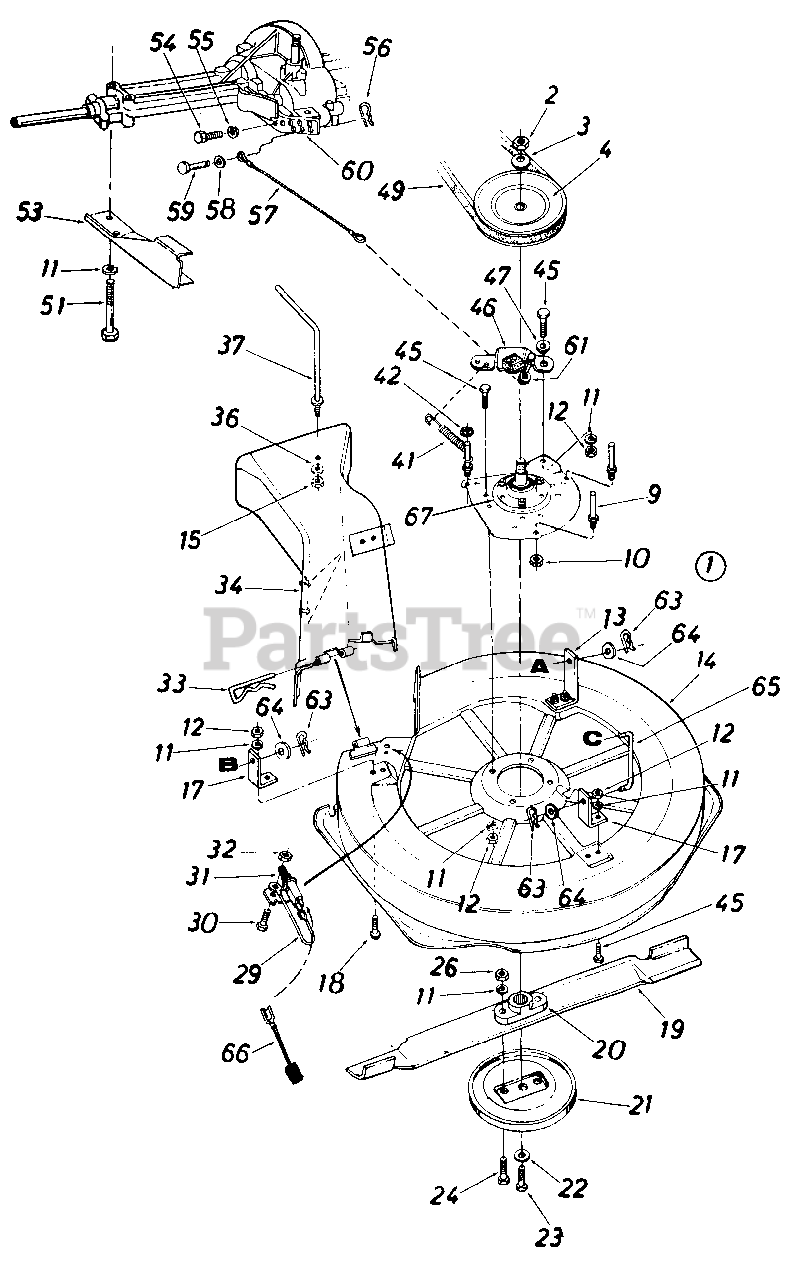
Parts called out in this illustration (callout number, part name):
1	30" R.D. Deck Ass'y. Comp.
2	Hex Jam Nut 5/8-18 Thd.
3	Bell-Wash. .630" I.D. x 1.25"
4	5/8 V-Pulley .75" I.D. x .7"
9	Stud 3/8-16 x 2.75" Lg.
10	Hex Jam Nut 3/8-16 Thd.
11	L-Wash. 5/16" I.D.
12	Hex Nut 5/16-18 Thd.
19	30" High Lift Blade
20	Blade Adapter
21	Scalp Plate
22	L-Wash. 3/8" I.D.
23	Hex Bolt 3/8-24 x 1.0
24	Hex Bolt 5/16-24 x 1.0" Lg.
26	Hex Nut 5/16-24 Thd.
29	Electrical Wire
30	Hex Bolt 1/4-20 x .50" Lg.
31	Safety Switch
32	Hex Nut 1/4-20 Thd.
33	Internal Cotter Pin
34	R.D. Chute Deflector
36	L-Wash. .32" I.D. x .62" O.D.
37	90ø Rod 5/16-18 Thd.
41	Extension Spring
42	Push Speed Nut
45	Hex Bolt 5/16-18 x .75
46	Blade Brake Brkt. Ass'y.
47	Shoulder Spacer .500" Dia.
49	"V"-Belt 1/2" x 52" Lg.
51	Hex Bolt 5/16-18 x 2.75"
55	L-Wash. 1/4" I.D.
56	Int. Cot. Pin 5/16" Dia.
57	Brake Cable 11.75" Lg.
58	Fl-Wash. .281" I.D. x .50
59	Clevis Pin 1/4" Dia.
60	Lower Inside Belt Guard
61	Cap Speed Nut 1/4" Rod
63	Int. Cotter Pin 1/2" Dia.
64	Fl-Wash. .531" I.D. x .930"
65	Deck Link 3.9" Lg.
66	Wire Lead
67	Blade Spindle Ass'y. Comp.
